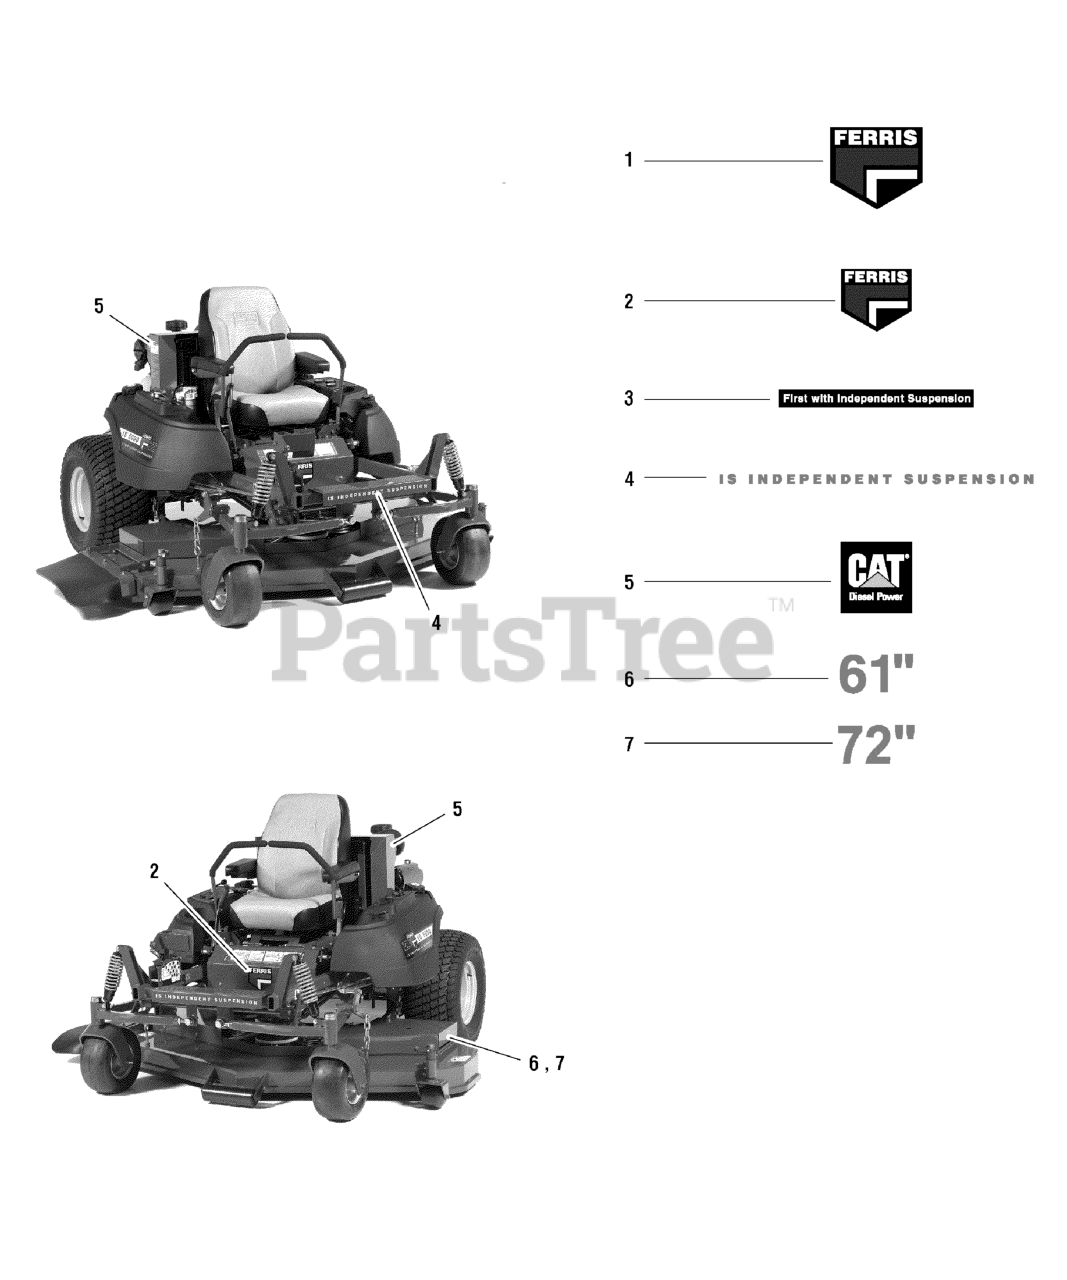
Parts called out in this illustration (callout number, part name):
1	DECAL, Ferris Logo, 6-3/8"
2	DECAL, Ferris Logo, 5"
3	DECAL, First w/ Independent Suspension
4	DECAL, IS Independent Suspension
5	DECAL, CAT Diesel Power
6	DECAL, 61"
7	DECAL, 72"
